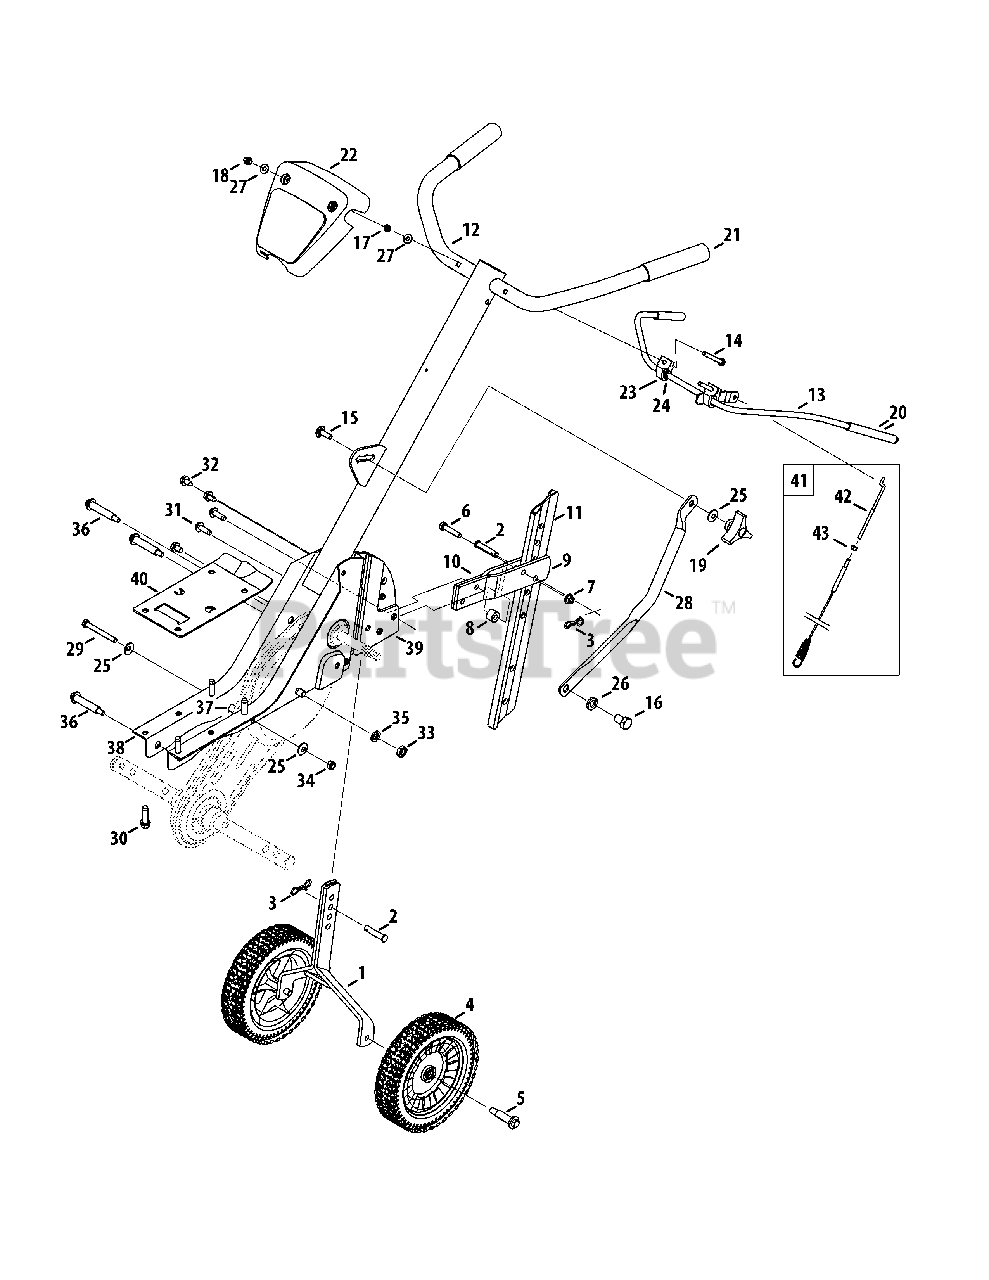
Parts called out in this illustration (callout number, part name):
1	Wheel Bracket Assembly
2	Clevis Pin, .375 x 1.75
3	Bow Tie Cotter Pin
4	Complete Wheel Assy. 8 x 1.75
5	Shoulder Screw, .496 x 1.445 3/8-16
6	Hex Head Screw, 5/16-18 x 1.50
7	Nut, 5/16-18, Flange Lock
8	Spacer, .325 ID x .75 OD x .520
9	Tail Bracket, LH
10	Tail Bracket, RH
11	Depth Bar
12	Complete Handle Assembly
13	Clutch Bail
14	Hex Head Screw, 1/4-20 x 2.25
15	Carriage Screw, 5/16-18 x 1.00
16	Hex Head Screw, 1/2-20 x .750
17	Jam Nut, 1/4-20
18	Nut, 1/4-20, Lock
19	Handle Knob
20	Grip, Clutch Bail
21	Grip, Handle
22	Handle Cover
23	Clutch Bail Holder
24	Flat Washer, .385 x .62 x .063
25	Bell Washer, .340 x .872 x .060
26	Lock Washer, 1/2
27	Flat Washer, .271 x .630 x .065
28	Handle Brace
29	Hex Head Screw, 5/16-18 x 2.75
30	SEMS Screw, 3/8-16
31	Self-Tapping Screw, 5/16-18 x 1.00
32	Self-Tapping Screw, 5/16-18 x .625
33	Jam Nut, 7/16-20
34	Nylon Hex Lock Nut, 5/16-18
35	Lock Washer, 7/16
36	Shoulder Screw, .475 x 2.11 5/16-18
37	Spacer, .47 OD x .96
38	Frame, RH
39	Frame, LH
40	Engine Mounting Plate
41	Forward Clutch Cable
42	Z-Fitting (incl. Ref 43)
43	Jam Nut
